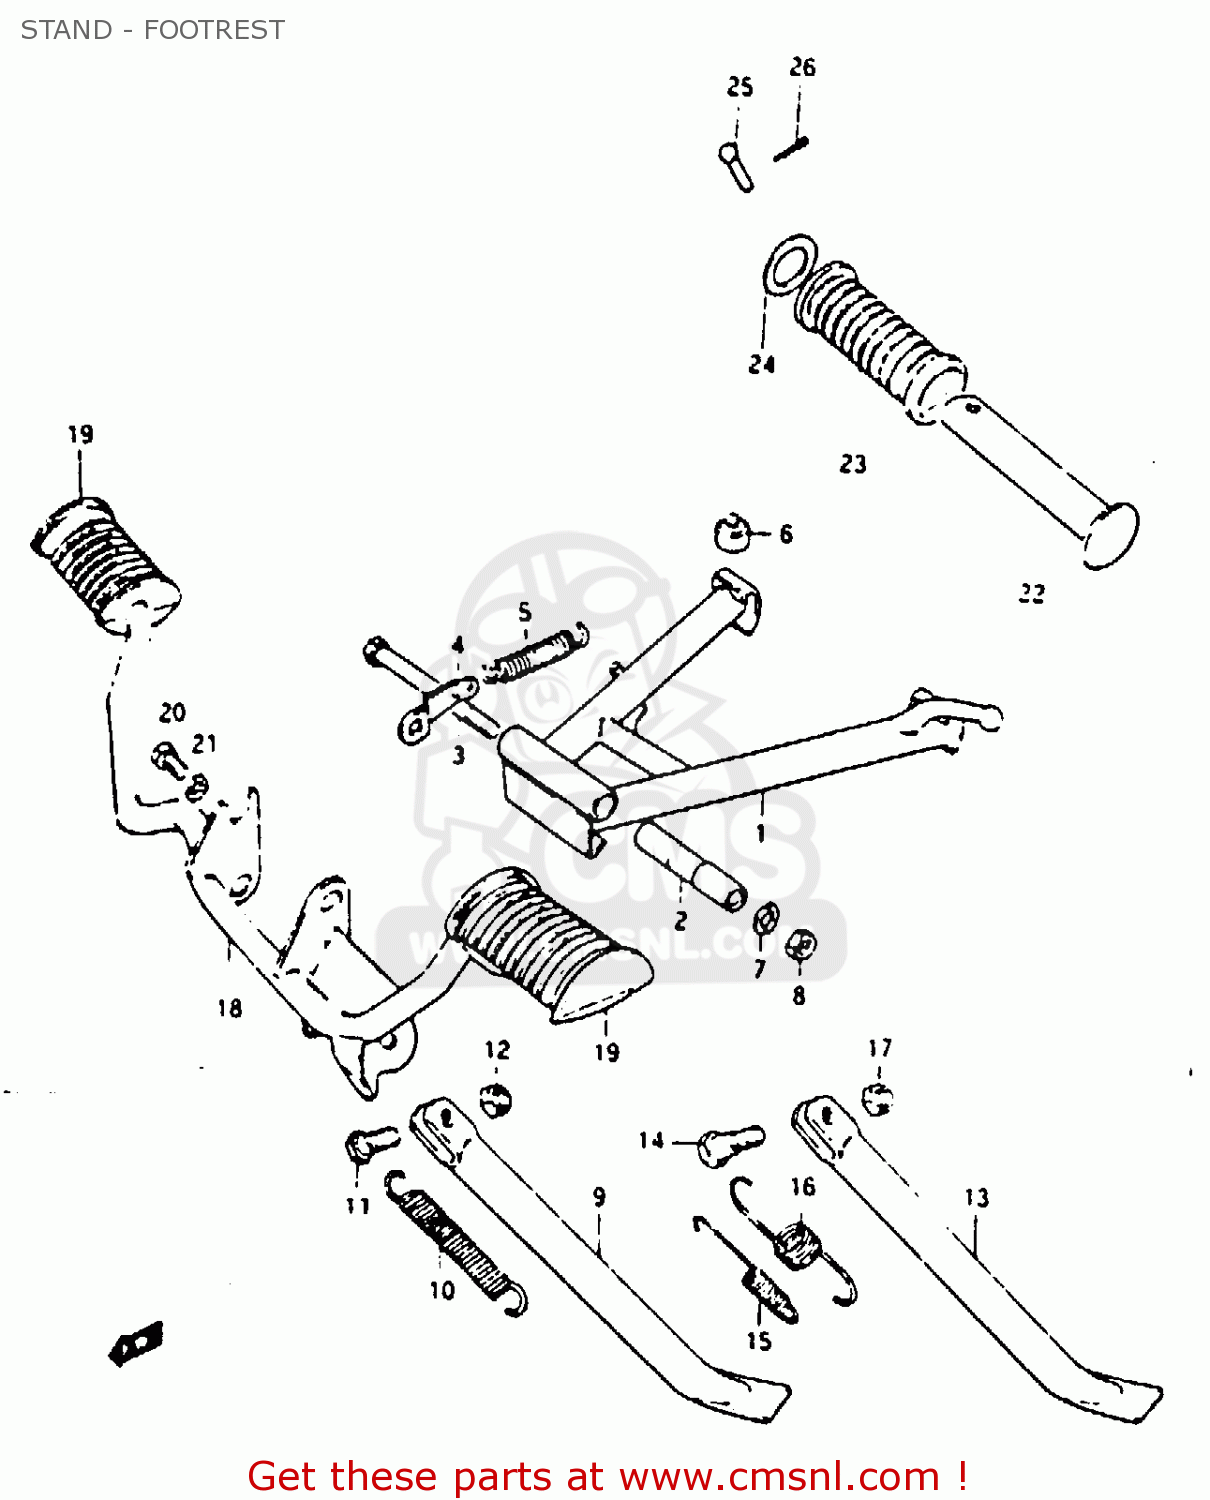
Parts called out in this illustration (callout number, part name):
1	STAND,CENTER
2	SPACER
3	BOLT(10X110)
4	HOOK,CTR STAND SPRING
5	SPRING
6	CUSHION
7	WASHER,LOCK,10
8	NUT
9	STAND,PROP
10	SPRING
11	BOLT
12	NUT
13	STAND, PROP
14	BOLT(10X28)
15	SPRING
16	SPRING, OUTER
17	NUT
18	BAR, FRONT FOOTREST
19	RUBBER,FR FOOTREST
20	BOLT,8X16
21	LOCK WASHER
22	BAR,FOOTREST RUBBER
23	RUBBER,PILLION FOOTREST
24	WASHER (19.5X32X2)
25	PIN
26	PIN 20X20
